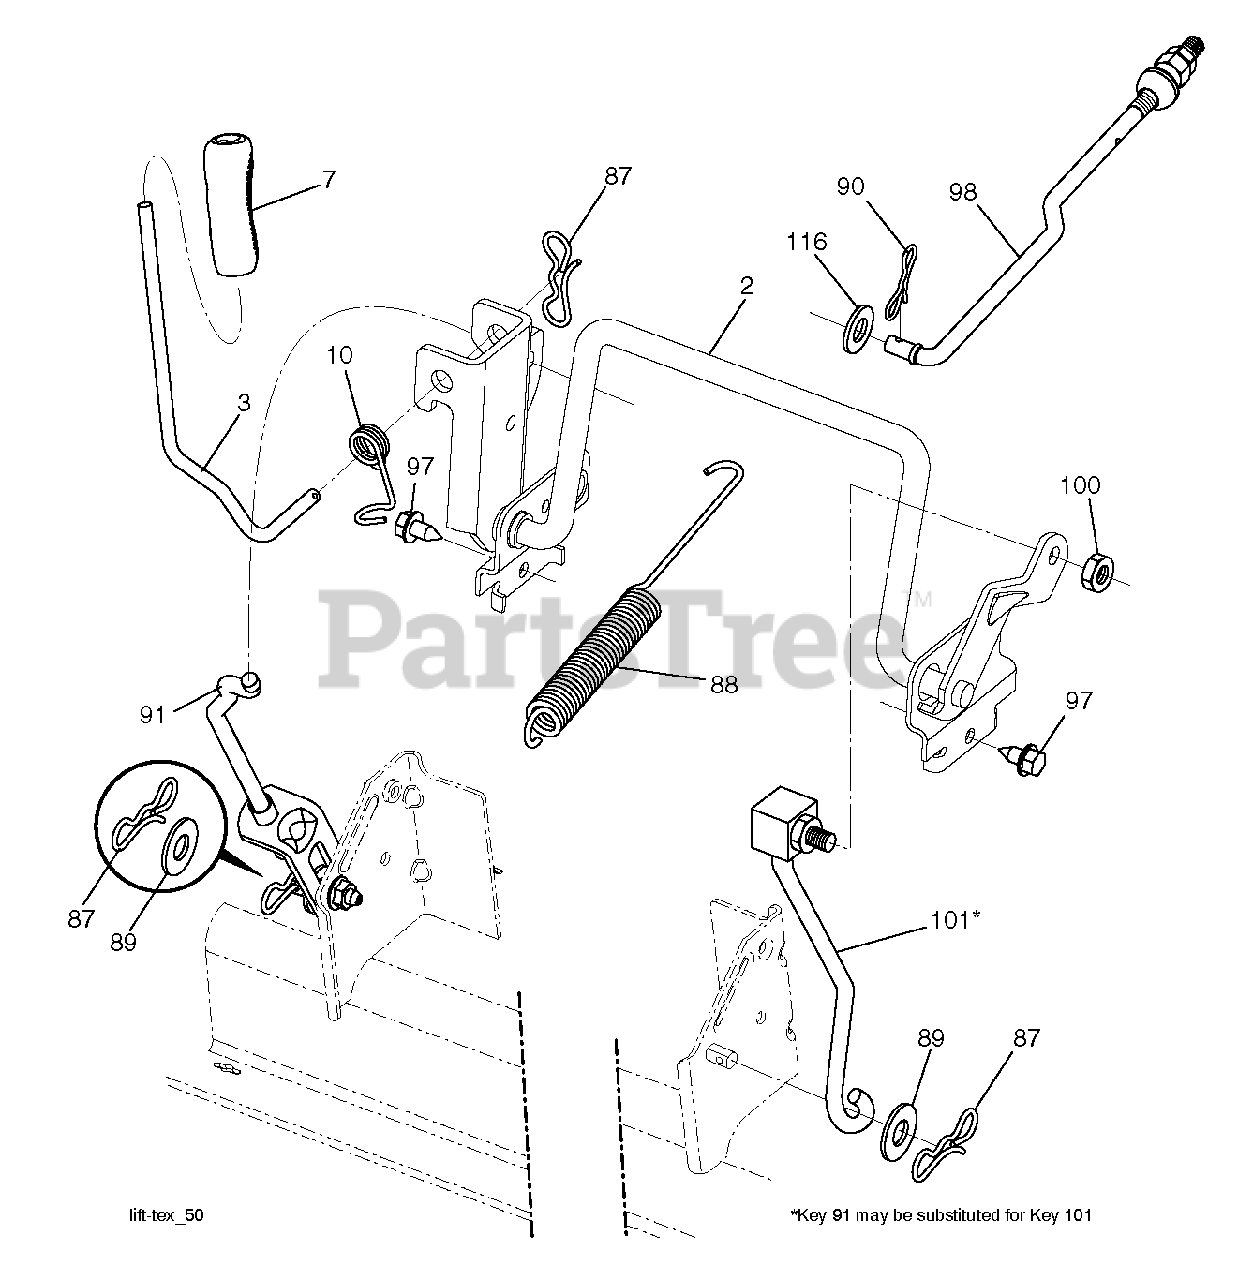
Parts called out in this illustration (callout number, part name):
2	SHAFT LIFT DECK WELD
3	LEVER.LIFT.HANDLE.LT
7	GRIP.HANDLE.LIFT.PVC.BLACK
10	SPRING.TORSION.LIFT.HANDLE
87	PIN.COTTER.7/16.BOW TI.
88	SPRING.DK.LIFT.97/107.TXCRDII
89	WASHER.CLEAR.ZINC
90	PIN.COTTER.5/16.BOW TI
91	LINK.ASM.LIFT.REAR
98	LINK.ASM.SUSP.FRONT.MW
100	LOCKNUT
101	LINK.ASM.LIFT.FIXE.38/42/46"
